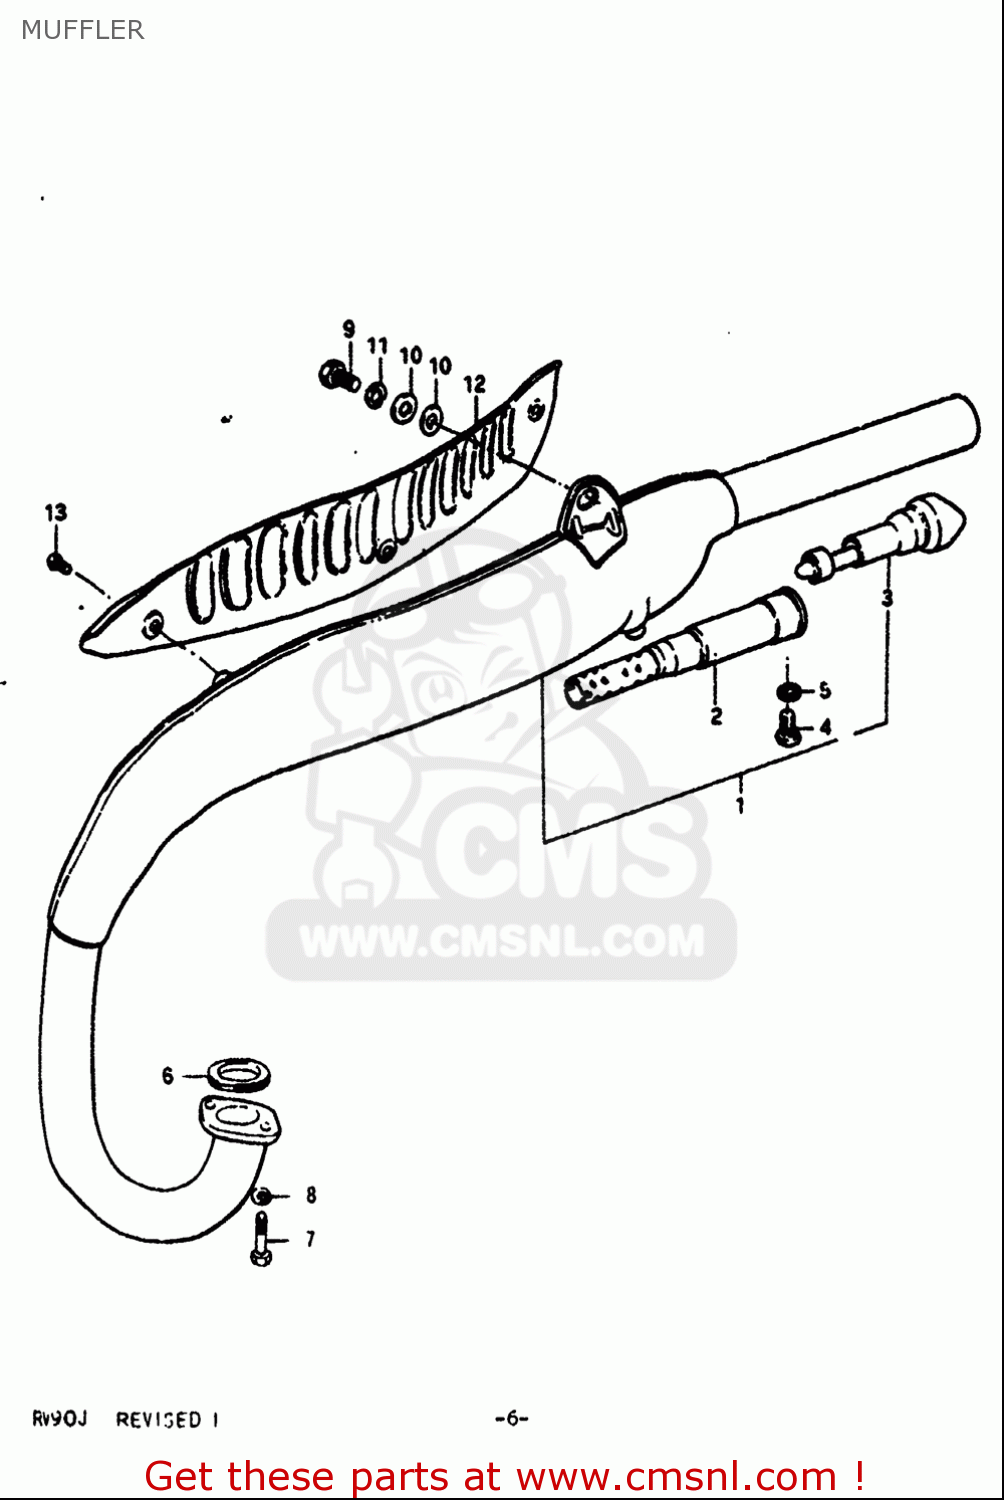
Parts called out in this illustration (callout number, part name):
4	SCREW(5X6)
5	WASHER,LOCK
6	GASKET,EXHAUST (NAS)
7	BOLT(8X27)
8	WASHER,LOCK
9	BOLT
10	WASHER
11	WASHER,LOCK
12	COVER,MUFFLER
13	SCREW
